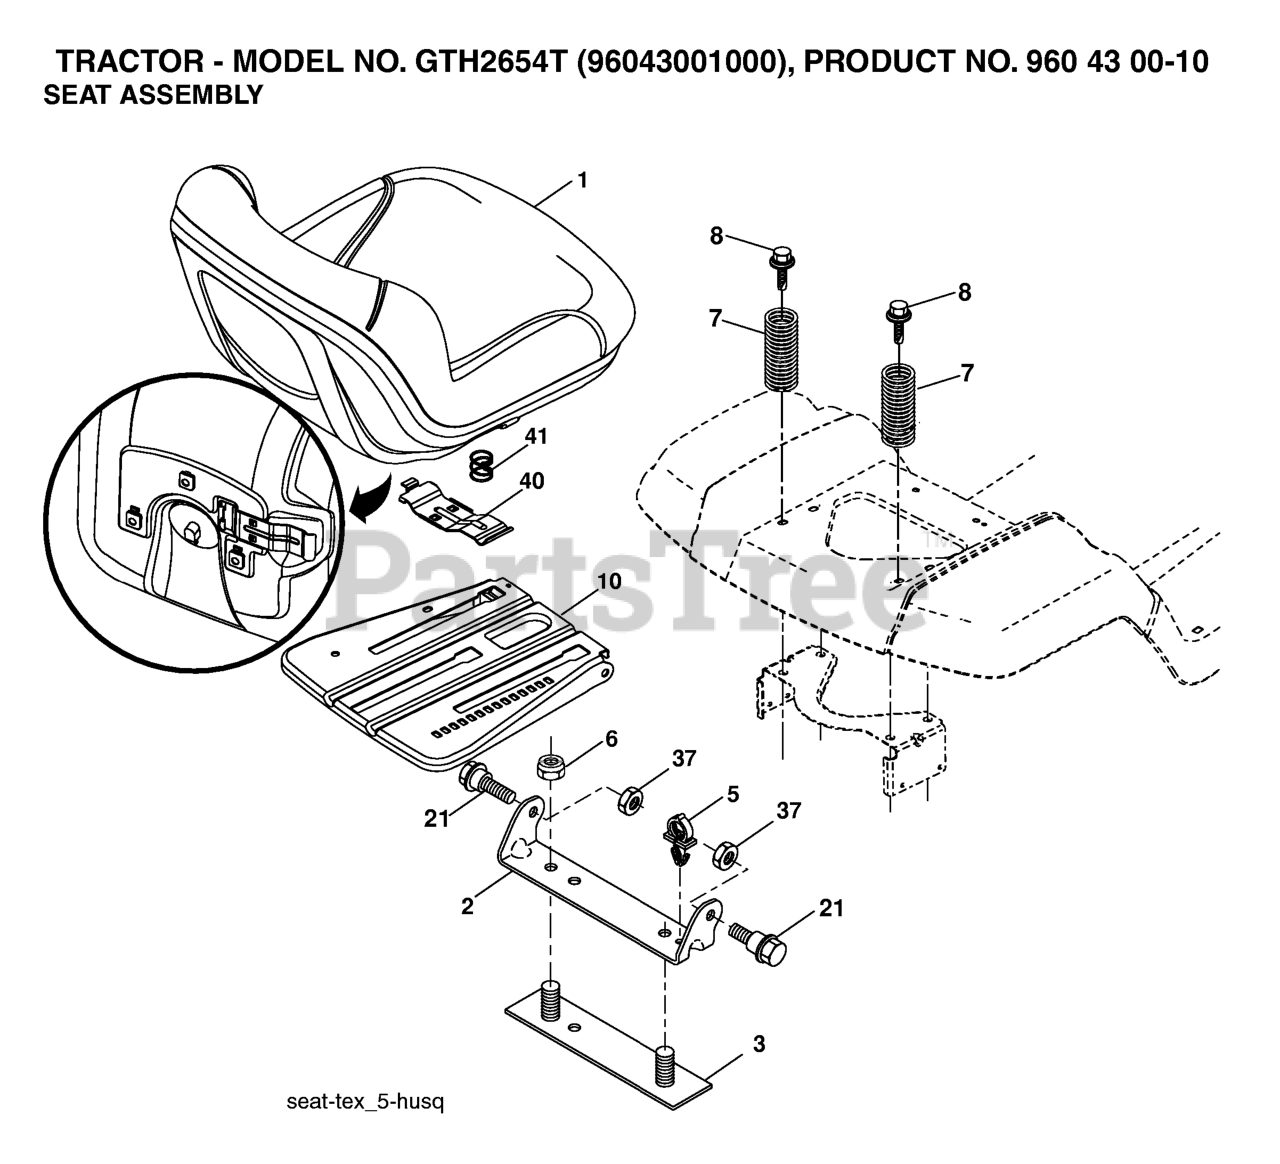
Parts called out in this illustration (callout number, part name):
1	SEAT.TH150.GRY.KB/SL.H
2	BRKT.PIVOT.FENDER
3	STRAP
6	NUT
7	SPRING COMPRESSION
8	BOLT.5/16-18UNCX3/4 W/SEMS.BLK
10	PAN.ASM.SEAT.3PT
21	BOLT.SHOULDER.5/16-18
37	NUT.71038.31-18.HEX.NYLOCK
40	HANDLE.SLIDE.SEAT.TEX.BLACK
41	SPRING.LATCH.SEAT.TEX
44	WASHER 13/32 X 2-3/8 X 12GA
